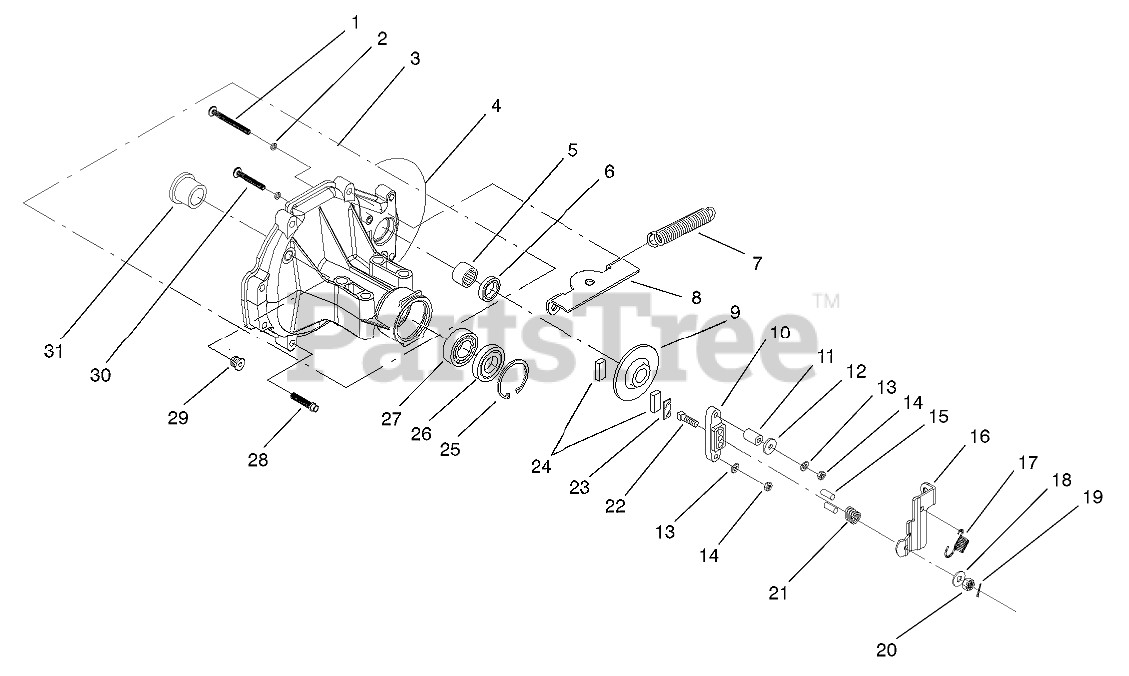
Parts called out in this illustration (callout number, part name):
2	O-RING
3	RH HOUSING ASM
4	SEALANT
5	BEARING-NEEDLE
6	SEAL-LIP
7	SPRING-RETURN
8	BRACKET-CRANK, BELL
9	DISK-BRAKE
10	YOKE-BRAKE
11	SPACER
12	WASHER
13	WASHER-LOCK
15	PIN-BRAKE
16	ARM-BRAKE
17	SPRING-ARM, BRAKE (BIAS)
18	WASHER
19	PIN-COTTER
20	NUT-CASTLE
21	SPRING-BRAKE, ANTI DRAG
22	BOLT-SQH
23	PUCK-PLATE
24	PUCK-BRAKE
25	RING-RETAINING
27	BEARING-BALL
28	SCREW-TTH
29	PLUG-THREAD, STRAIGHT
31	BEARING-FLANGE
